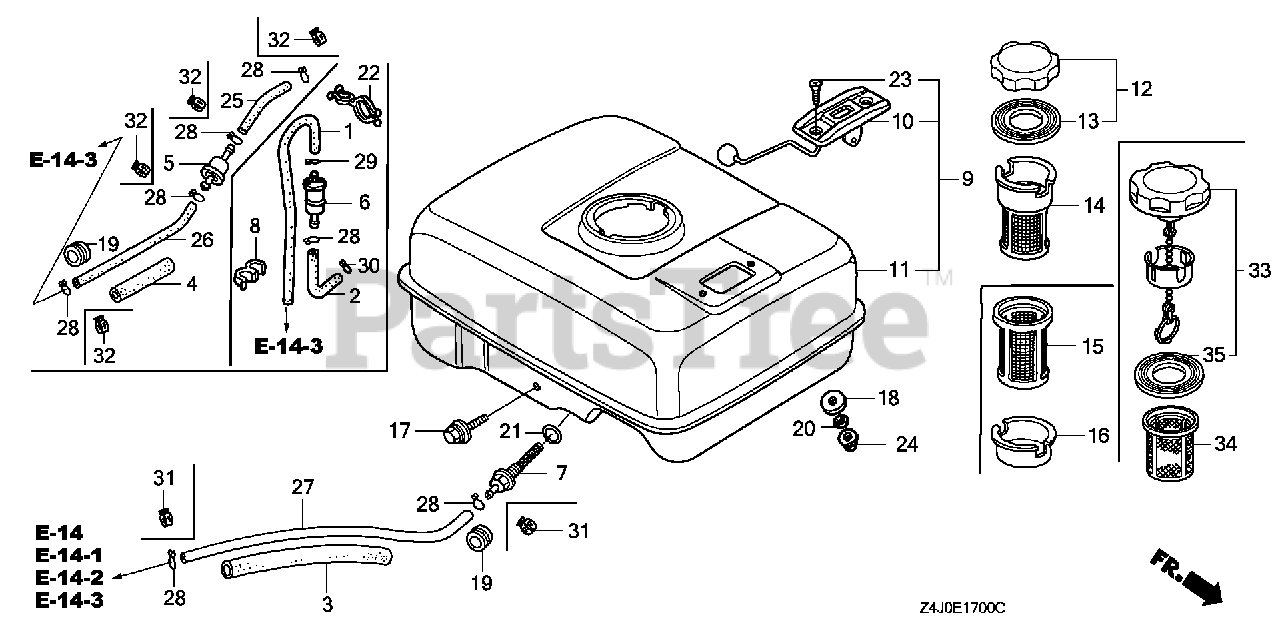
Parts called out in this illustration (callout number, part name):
3	RUBBER, SUPPORTER (107MM)
7	JOINT, FUEL TANK (NOT AVAILABLE)
7	JOINT, FUEL TANK
11	TANK, FUEL *NH31* (MCKINLEY WHITE) Use up to Engine SN 3033315.
12	CAP, FUEL FILLER (CHROME PLATED)
13	GASKET, FUEL FILLER CAP (39X62X3) (TOUYOUSYA)
17	BOLT, FLANGE (6X29)
21	O-RING (14MM) (ARAI) Use up to Engine SN 2949254.
21	O-RING (14MM) (NOK)
24	NUT, FLANGE (6MM)
27	TUBE, FUEL (4.5X140) (FKM)
27	BULK HOSE, FUEL (4.5X3000) (Honda Code 5137104). (4.5X140)
28	CLIP, TUBE (B8)
31	CLIP, TUBE (D8)
33	CAP, FUEL FILLER
35	GASKET, FUEL FILLER CAP
35	GASKET, FUEL FILLER CAP (39X62X3)
